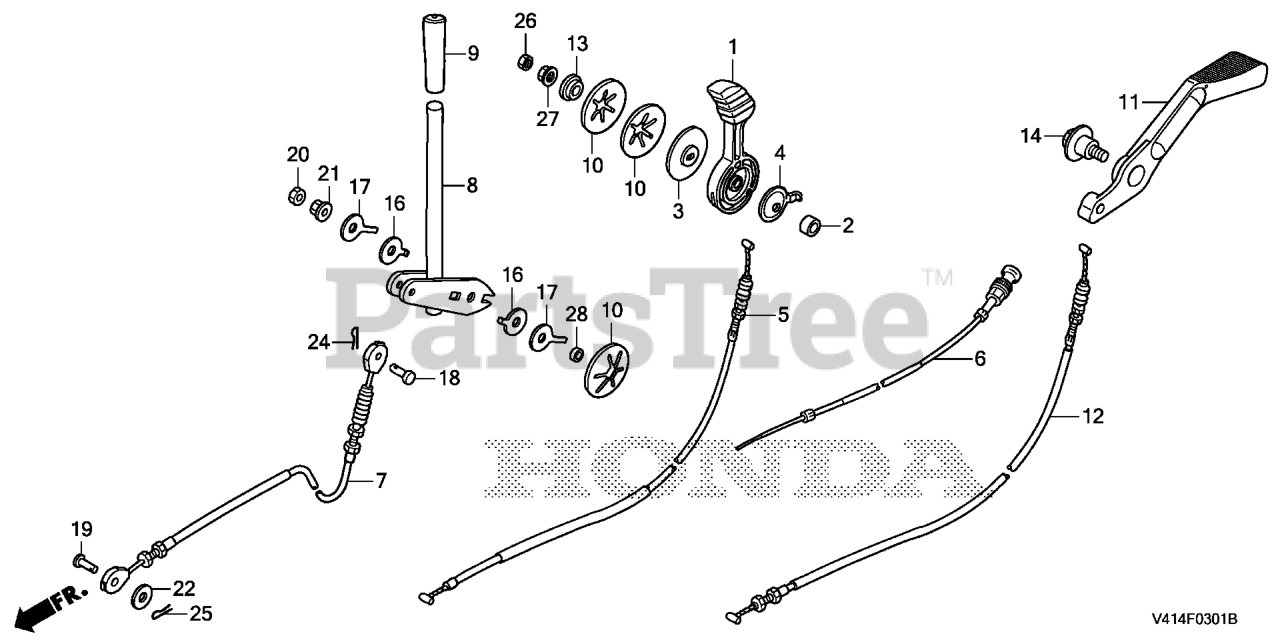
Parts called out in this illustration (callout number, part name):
1	LEVER, THROTTLE
2	COLLAR, THROTTLE PIN
3	PLATE, THROTTLE LEVER
4	SEAT, SPRING
5	CABLE, THROTTLE
6	CABLE, CHOKE
7	CABLE, CHANGE
8	LEVER, CHANGE
9	GRIP, CHANGE LEVER (ORANGE)
10	SPRING, ADJUSTING ARM
11	LEVER, HEIGHT ADJUSTING
12	CABLE, HEIGHT ADJUSTING
13	COLLAR, CHUTE GUIDE
14	BOLT, SPECIAL (8X22)
16	WASHER, FRICTION
17	WASHER, FRICTION SETTING
19	PIN (8X34)
20	NUT,HEX 8MM
21	NUT-WASHER (8MM)
22	WASHER, PLAIN (8MM)
24	PIN, COTTER (1.6X12)
25	PIN, SPLIT
26	NUT, HEX. (6MM)
27	NUT, FLANGE (6MM)
28	TUBE, RUBBER (7.3X12.5X5.5)
